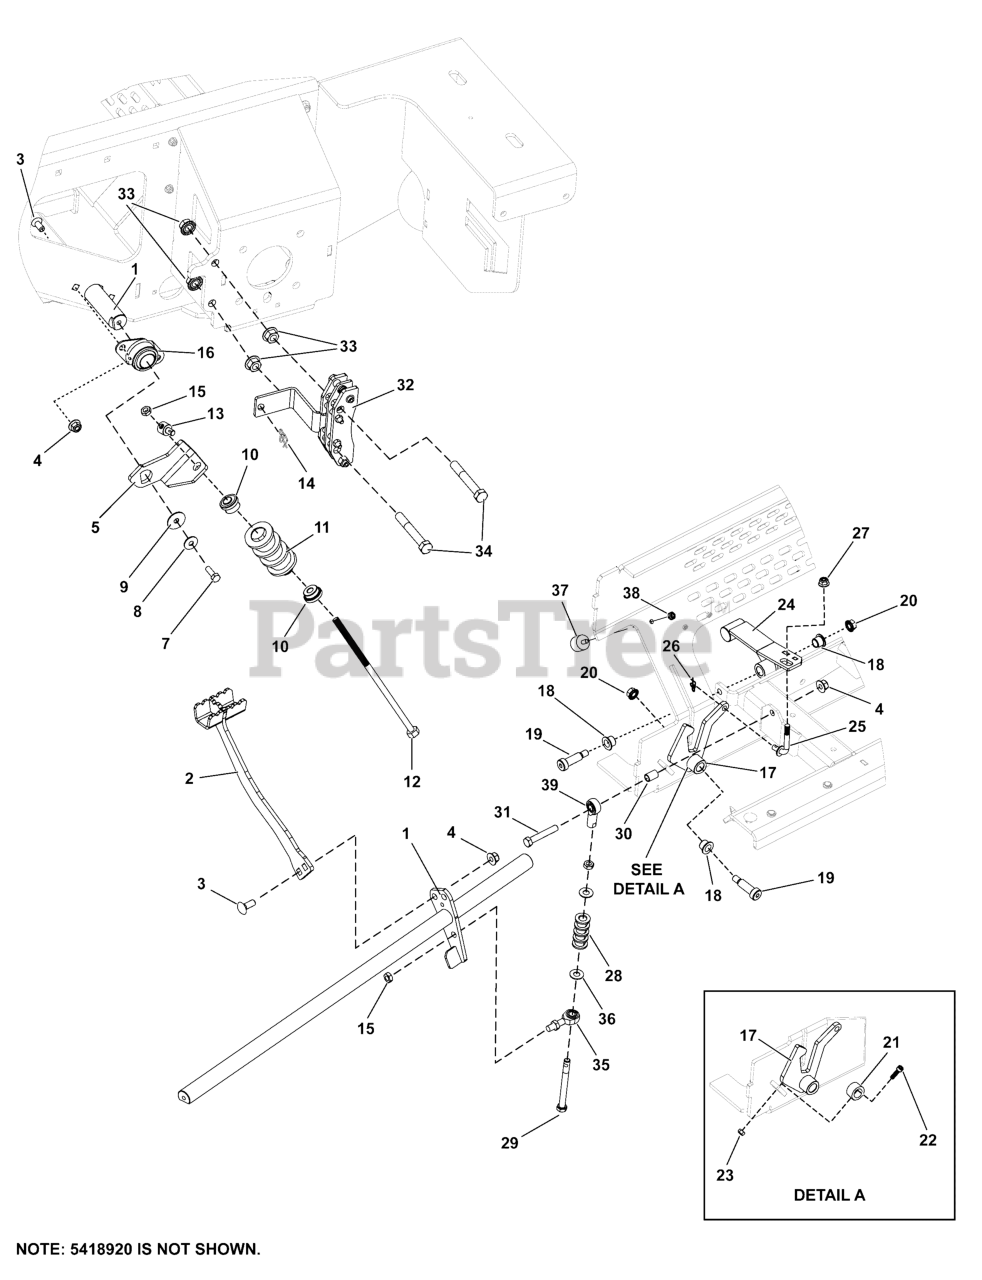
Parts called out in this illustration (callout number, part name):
1	WELD, PARK BRAKE
2	WELD, PARK BRAKE PEDAL
3	BLT-RDHDSQNK, .375"-16 X 1.000" SS188
4	NUT-HEX-NYLK, FLG .375"-16 SS188
5	ARM, BRAKE ACTUATE LH
6	ARM, BRAKE ACTUATE RH
7	SCR-CAP, HEX .3125"-18 X 1.000" SS188
8	WSHR-SS, BLV .322"X.938"X.072" 17-7PH
9	WSHR-SS, FLT .348"X1.250"X.065" FEN
10	BSHG, STEP .343"X1.25"-1.00",.562"SS
11	SPRG, ELA 1.00" X 3.42", 103#/IN
12	ROD, .375"-24 X 3.50" - 9.53" OAL SS
13	SWIVEL, Ø.3125-24, Ø.370 POST SS
14	RING, RUE .375" SS
15	NUT-HEX, JAM .375"-24 SS188
16	BRG, BRZ 1.00"ID X 3.125" CTR SIDE FLG
17	WELD, BRAKE LATCH
18	BSHG-FL, .500" X .625" X .500", .875"x .062" IR
19	BLT-SLDR,SH.50"X1.25",.375"-16X.63"SS188
20	NUT-HEX-FGLK, .375"-16 SS188
21	SPRG, BMP .97" X 1.12" 50#PDF
22	SCR-CAP, SH #10-24 X .750" SS188
23	NUT-HEX-NYLK, #10-24 SS188
24	WELD, BRAKE RELEASE
25	LINK, BRAKE RELEASE
26	RING, RUE .3125" SS
27	NUT-HEX-NYLK, FLG .3125"-18 SS188
28	SPRG, ELA .500" X 2.26", 33#/IN
29	SCREWCAP 3/8-24 X 4" G8 W/ PATCH
30	SPCR-SS, 303 .391" X .500" X .750"
31	SCR-CAP, HEX .375"-16 X 2.250" SS188
32	COMPACT CALIPER, AUSCO (86978)
33	NUT-HEX-FGLK, .500"-13 SS188
34	SCR-CAP, HEX .500"-13 X 3.500" SS188
35	BALL JOINT, 3/8-24 Male
36	WSHR-STL, FLT .406" X .875" X .050" IS SS188
37	BUMPER, RUBBER, 1/4-20
38	NUT-HEX-FGLK, .250"-20 SS188
39	BALL JOINT, 3/8-24 FEMALE
